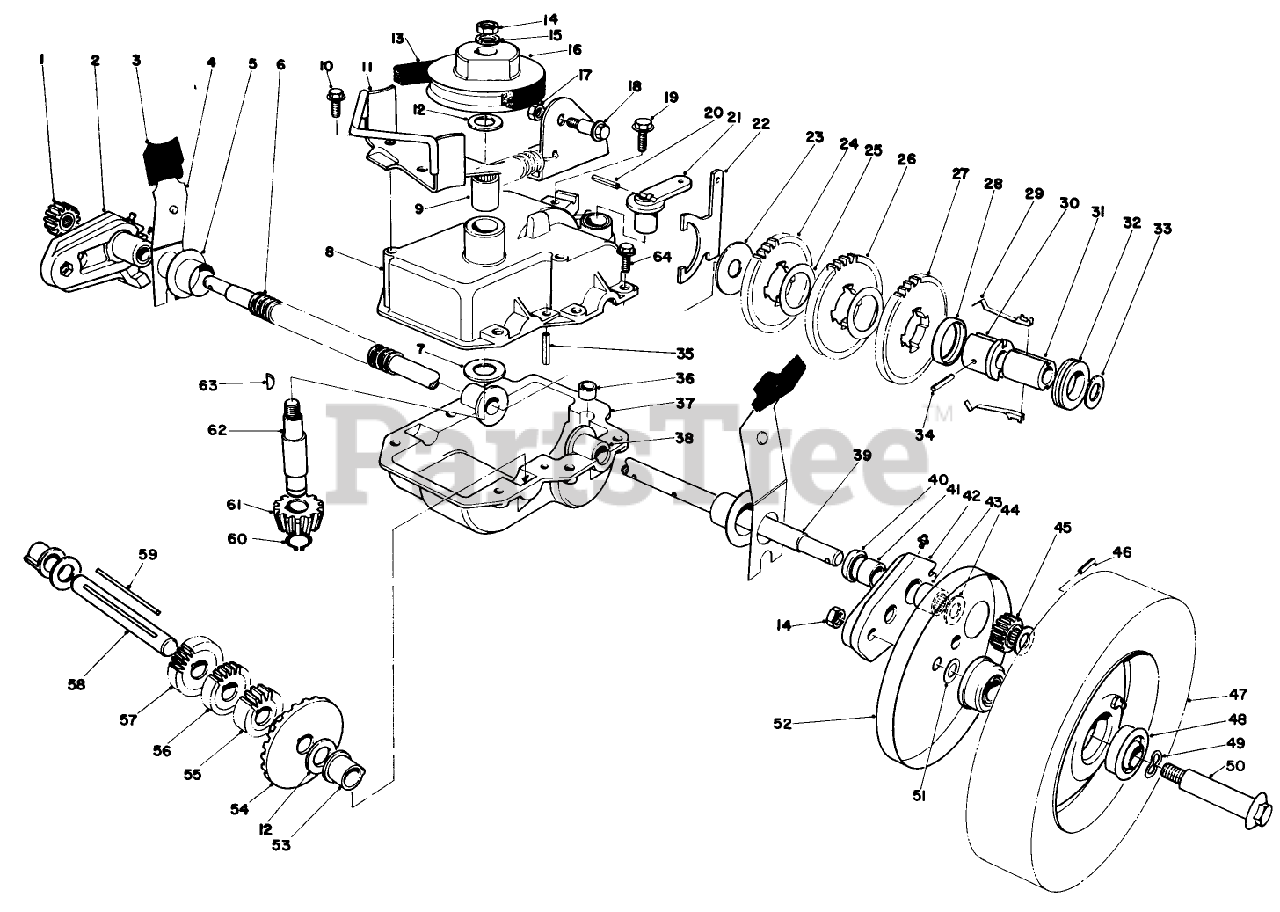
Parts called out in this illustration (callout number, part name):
1	RH CLUTCH & PINION
3	KNOB-ARM
5	CAP-END
6	CONDUIT-CONVOLUTED, SPLIT
8	DISC PRC4
12	Washer
13	V-BELT
15	Washer
16	DISC SEE PRC4
18	SHOULDER BOLT
19	SCREW-THD ROLL, HWH
20	PIN-SPRING
21	LEVER-SHIFT
23	WASHER
25	Washer
27	GEAR-42T
31	SLEEVE
32	COLLAR-SHIFT
33	Washer
35	ROLL PIN 3/16 X 1 IN
36	BUSHING-YOKE
39	OUTPUT SHAFT
41	Bushing
44	WASHER
45	LH CLUTCH & PINION
48	BEARING-BALL
49	SPRING WASHER
50	Wheel Bolt
51	WASHER
55	14 T GEAR
60	RING-RETAINING
61	PINION-BEVEL
63	KEY-WOODRUFF
64	SCREW-HWH, THREAD ROLL
